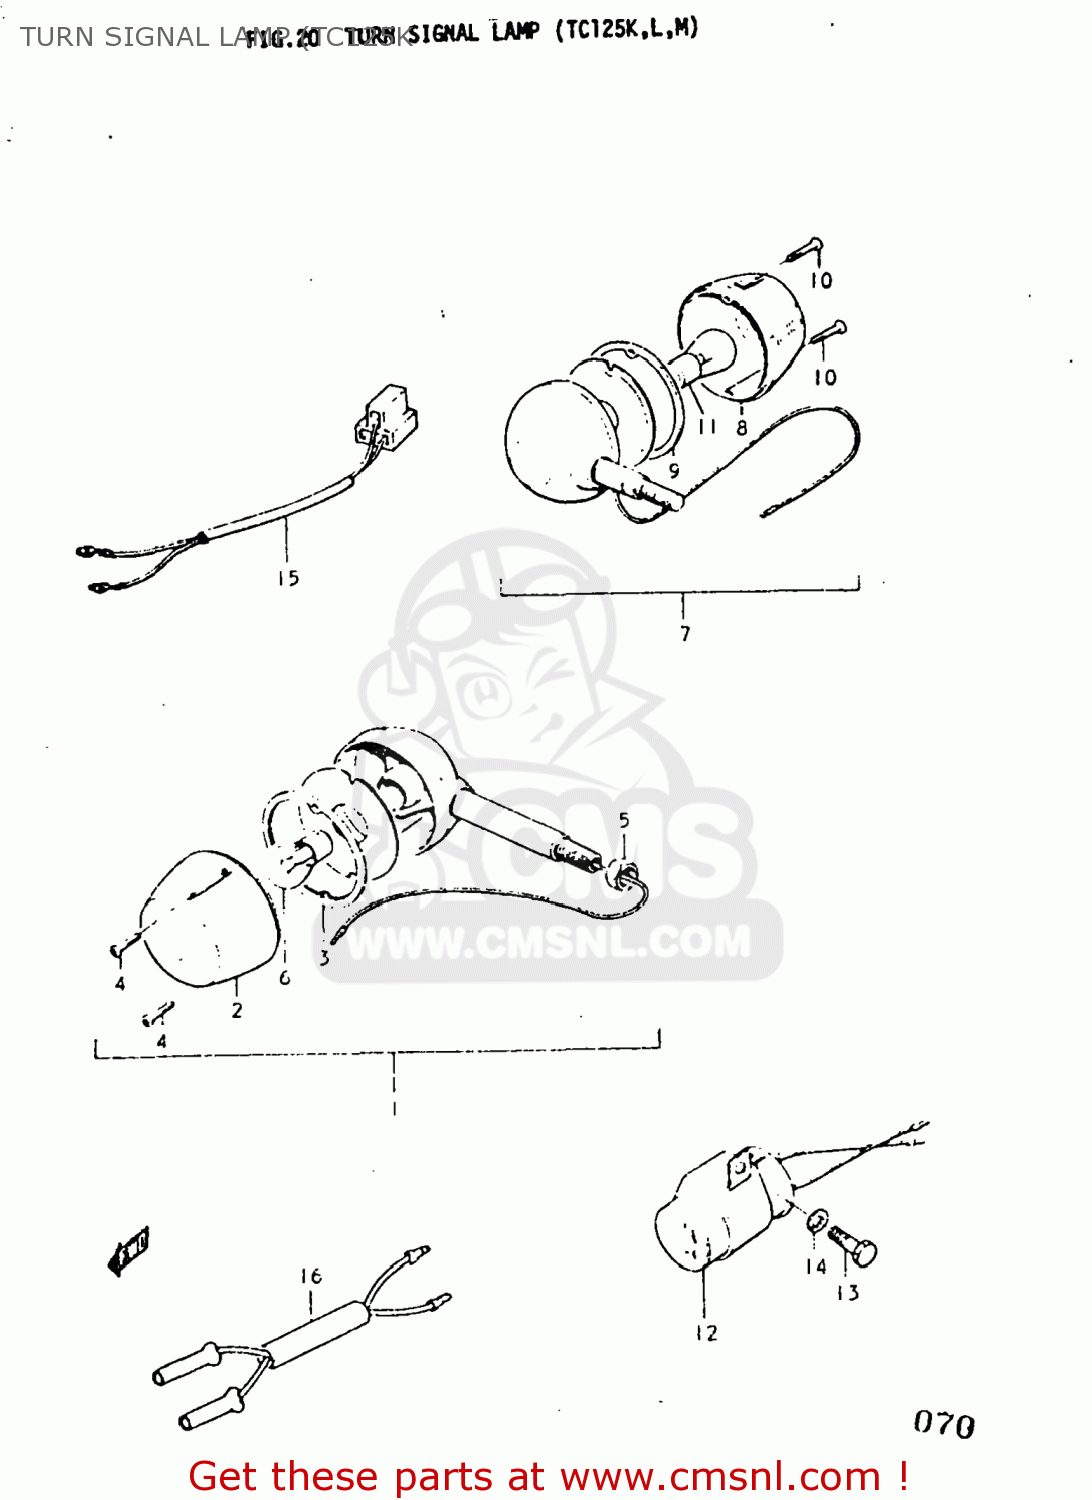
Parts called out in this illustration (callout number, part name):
1	LAMP ASSEMBLY,FRONT TURN SIGNAL
2	LENS,TURNSIGNAL
3	GASKET,TURNSIGNAL LENS (NAS)
4	SCREW
5	NUT
6	BULB(6V17W,STANLEY,A4513A)
7	LAMP ASSEMBLY,REAR TURN SIGNAL
8	LENS,TURNSIGNAL
9	GASKET,TURNSIGNAL LENS (NAS)
10	SCREW
11	BULB(6V17W,STANLEY,A4513A)
12	RELAY,TURN SIGNAL
13	BOLT
14	LOCK WASHER
15	WIRE
16	WIRE,REAR TURN SIGNAL,LEFT
